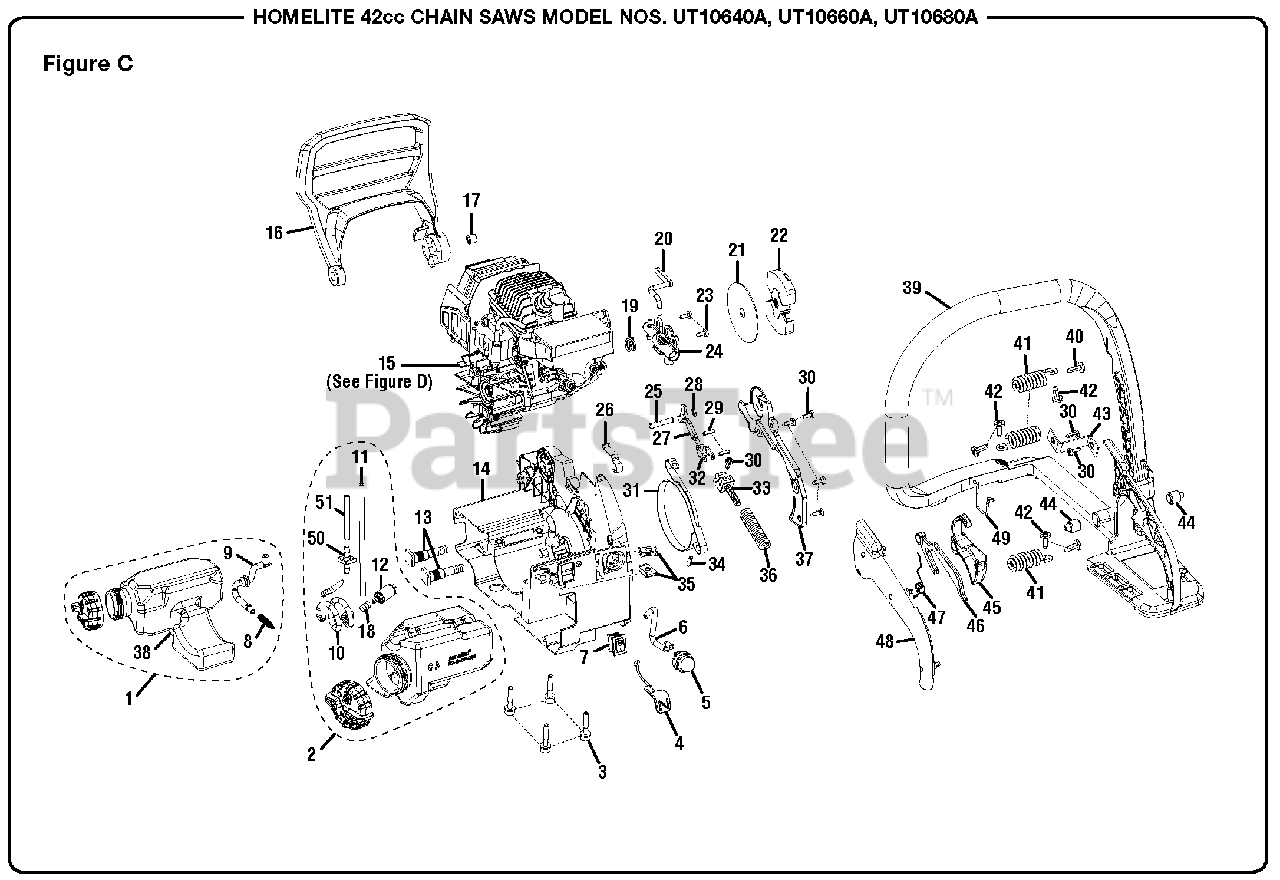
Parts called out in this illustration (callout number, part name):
1	Oil Tank & Cap Assembly
2	Fuel Tank & Cap Assembly
3	Screw (M5 x 28 mm)
4	Choke Lever
5	Primer Bulb
6	Primer Bulb Inlet Tube (73 mm)
8	Cone Spring
9	Oil Pump Inlet Tube
10	Fuel Line Inlet (Helical)
11	Fuel Line (220 mm)
12	Fuel Filter
13	Guide Bar Bolt (5/16-18)
14	Main Chassis
15	Engine Assembly
16	Front Hand Guard
17	Hand Guard Insert
18	Hose Clamp
19	Oil Pump Gear Spring
20	Oil Pump Outlet Tube
21	Thrust Washer
22	Clutch Assembly
23	Screw (M4 x 9.5 mm)
24	Oil Pump Assembly
25	Chain Brake Pin
27	Chain Break Pivot
28	E-Ring
29	Spring Pin
30	Screw (M4 x 12 mm)
31	Brake Band
32	Chain Brake Linkage
33	Spring Guide
34	Spring Pin
35	Speed Nut ("U"-Type)
36	Chain Brake Spring
37	Chain Brake Cover
39	Rear Handle
40	Screw (10-24 x 5/8 in.)
41	Isolator Spring
42	Screw (10-14 x 16 mm)
43	Anti-Vibe Strap
46	Lock-Out Lever
47	Trigger Return Spring
48	Rear Handle Cover
49	Throttle Rod
50	Fuel Fitting
51	Fuel Line Inlet (51 mm)
